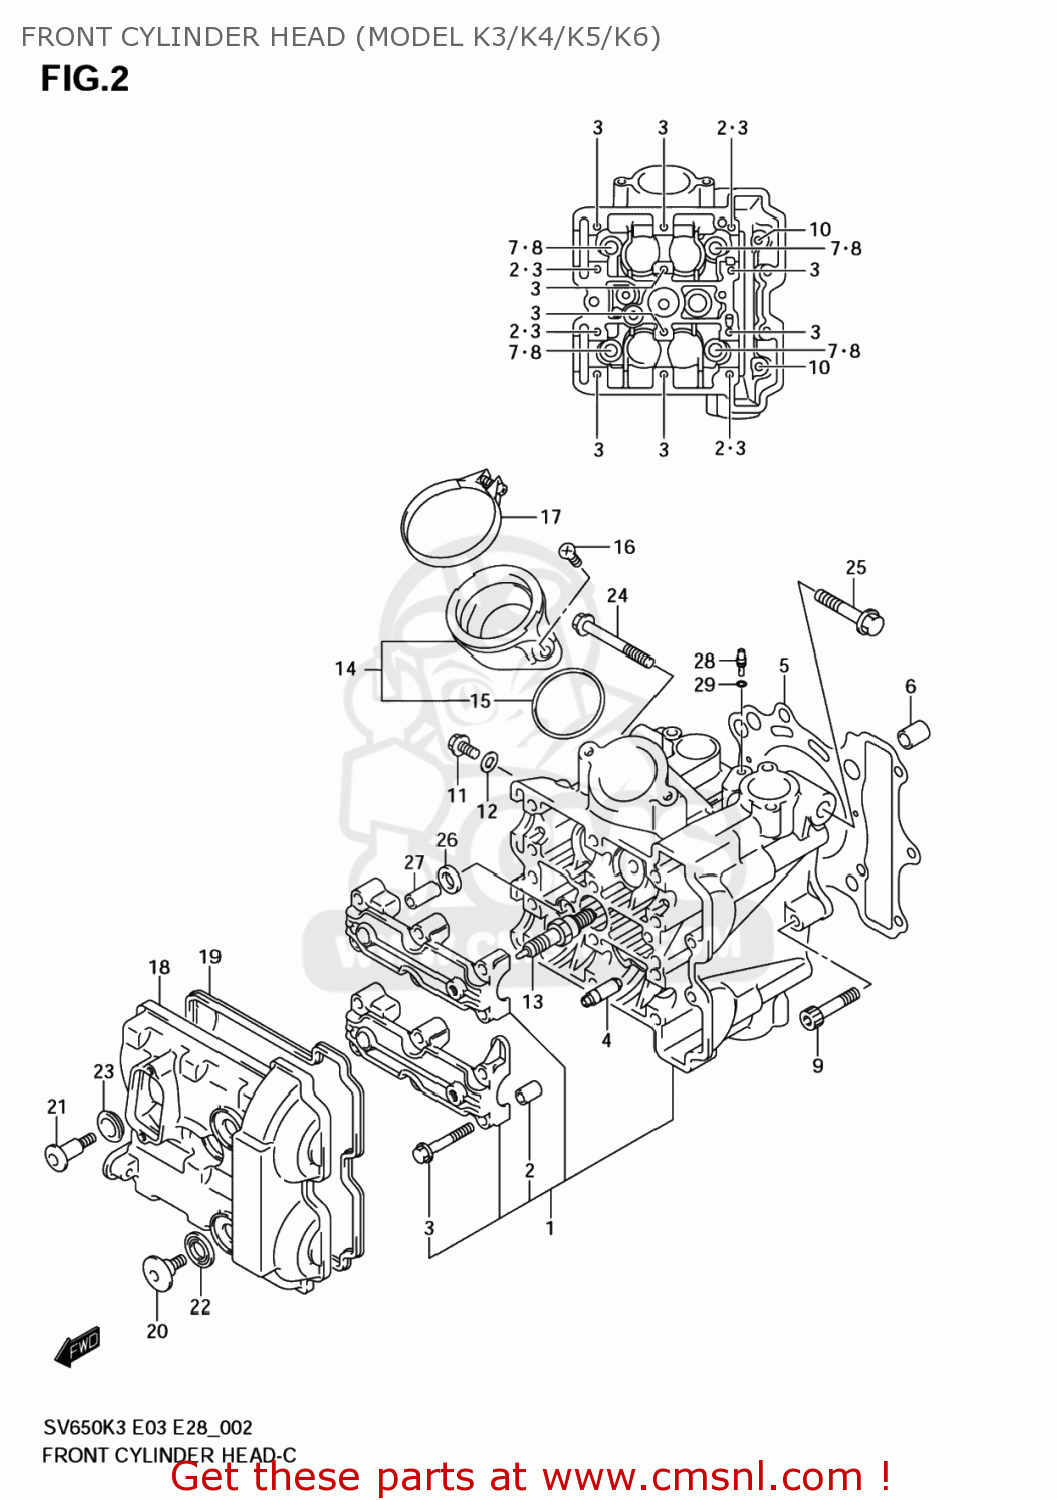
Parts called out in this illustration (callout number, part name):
1	HEAD ASSY,CYLINDER FR
2	PIN(6.2X8X11)
3	BOLT(6X39)
4	GUIDE,VALVE
5	GASKET,CYLINDER HEAD (NAS)
6	PIN
7	WASHER(10.5X19X2)
8	BOLT(10X160)
9	BOLT
10	BOLT(6X70)
11	BOLT
12	GASKET(5.8X13X1.2) (NAS)
13	PLUG,SPARK(CR8E)
14	PIPE ASSY,INTAKE FR
15	O RING(D:2.4,ID:47X42)
16	SCREW ,6X16
17	CLAMP
18	COVER,CYLINDER HEAD FR
19	GASKET,CYLINDER HEAD COVER (NAS)
20	BOLT(7X17.5)
21	BOLT(7X31)
22	WASHER(10.6X25.5X2.3)
23	CUSHION,HEAD COVER BOLT
24	BOLT(10X105)
25	BOLT
26	GASKET,2ND AIR PASSAGE (NAS)
27	PIN(6.2X8X16)
28	JET(8)
29	O RING(D:1.2,ID:4)
